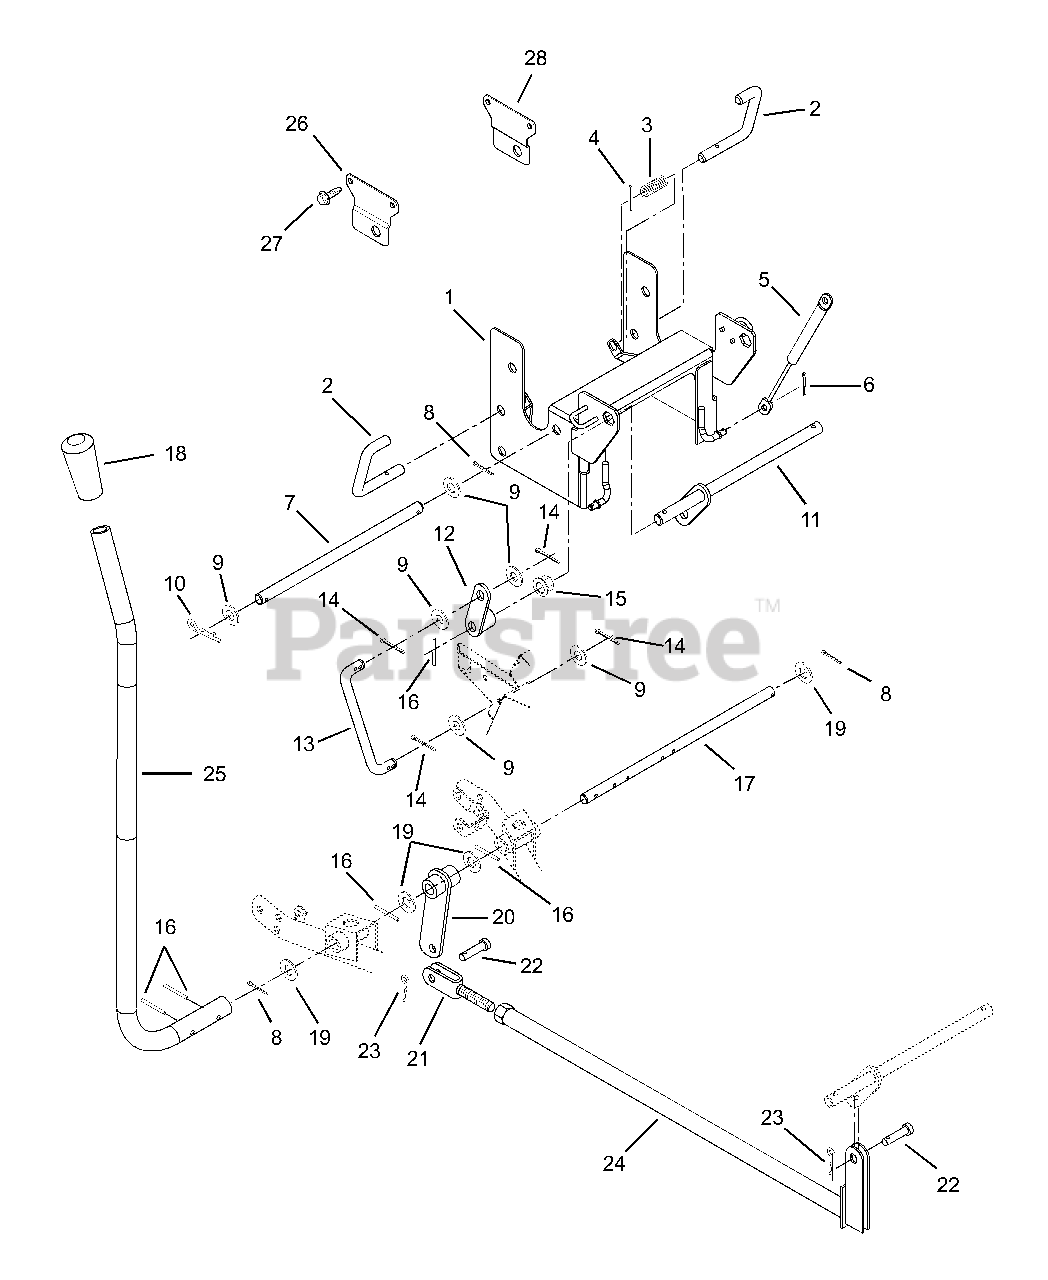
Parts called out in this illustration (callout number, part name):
1	Frame-Pivot
2	Pin-Latch
3	Spring-Compression .072 x .77 x 1.75
4	Pin-Roll .188 x 1.00
5	Spring-Gas Compression .315 x .75 x 10.00
6	Pin-Cotter .12 x .75
7	Rod-Pivot
8	Pin-Cotter .12 x 1.25
9	Washer-Flat-Steel .656 x 1.312 x .095
10	Pin-Air Internal .17 x .68 x 3.50
11	Pivot Rod
12	Lever-Right Hand
14	Pin-Cotter .12 x 1.0
15	Bushing-Flange .750 x .873 Hex x .53 x 1.18
16	Pin-Grove .250 x 1.50
17	Pivot Rod
18	Grip-Handle Bar
19	Washer-Flat-Steel .754 x 1.125 x .062
22	Clevis Pin .491/.496 x 1.25
23	Pin-Hair Cotter Internal .14 x .43 x 2.75
24	Lift Tube
25	Lever
26	Mount-Pivot Frame-RH (035)
27	Screw-Tapping .38-16 x .50 (035)
28	Mount-Pivot Frame-LH (035)
